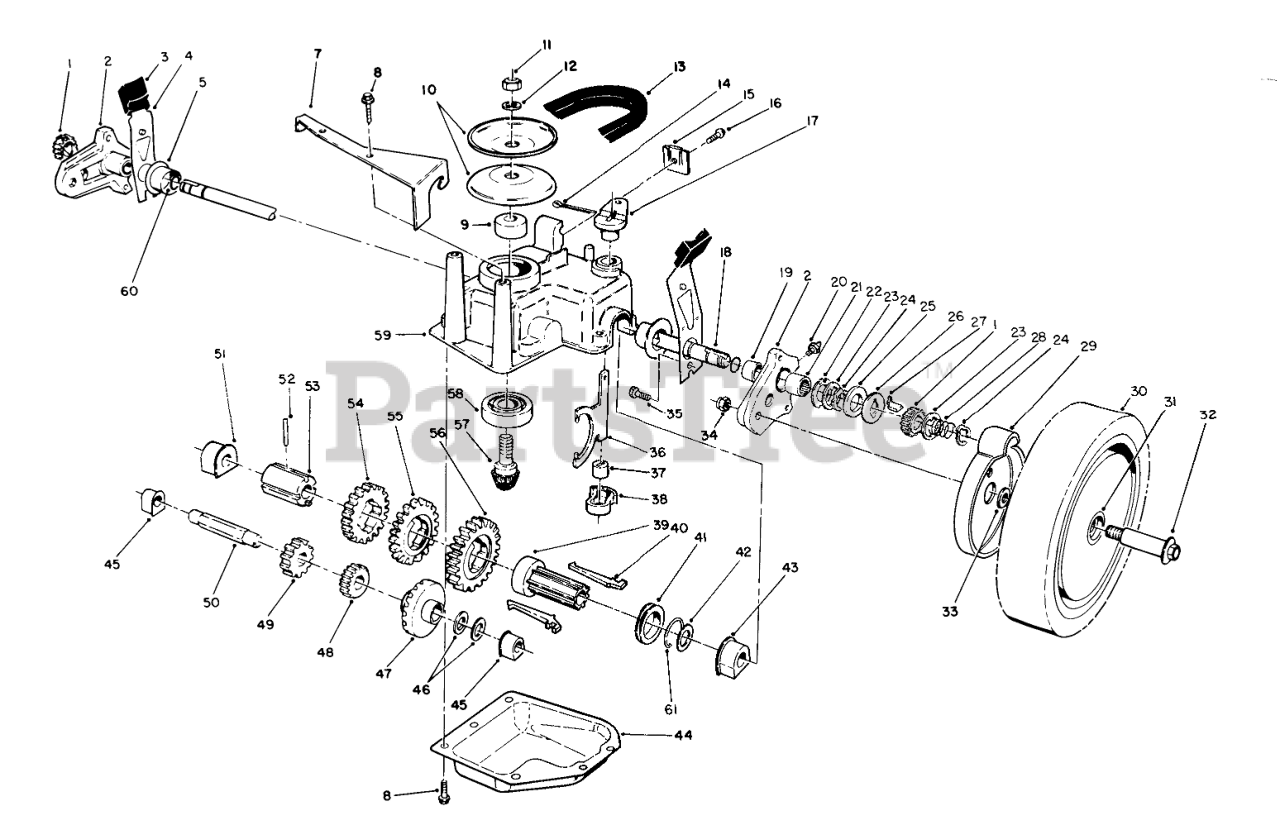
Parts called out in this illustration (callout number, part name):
1	GEAR-PINION
2	Pivot Arm Assembly (Incl. Ref #19, 20, & 21)
3	KNOB-ARM
4	SPRING ARM ASM SP
5	CAP-END
7	Bracket-Guide
8	SCREW-HWHTF
9	SPACER
10	Pulley Half
11	NUT-HEX
12	WASHER-FLAT
13	V-BELT E
14	PIN-COTTER
15	Cable Clamp
16	SCREW-HWHTF
17	SHIFT LEVER
18	SHAFT-OUTPUT
19	BUSHING
20	FITTING-GREASE
21	BEARING-ROLLER
22	WASHER-ARM, PIVOT
23	WASHER-THRUST, KEYED
24	RING-CLIP, LOCKING
25	RING-FRICTION
26	WASHER-CLUTCH
27	KEY-ROCKING, LH
28	SPRING-COMPRESSION
29	COVER-WHEEL
30	Wheel-Tire & Gear Ass-y (Incl. Ref. #31)
31	BUSHING
32	WHEEL BOLT
33	SPACER-COVER, WHEEL
34	Nut
35	SCREW-HWH
36	YOKE-SHIFT
37	BUSHING-YOKE
38	RETAINER-FORK, SHIFT
39	SLEEVE-KEY, SHIFT
40	KEY-SHIFT
41	COLLAR-SHIFT
42	WASHER-PLAIN
43	BUSHING-OUTPUT
44	Cover-Gearcase
45	BUSHING
46	WASHER-THRUST
47	Gear-Bevel
48	PINION-20T
49	PINION-25T
50	SHAFT-INTERMEDIATE
51	BUSHING
52	PIN-SPRING
53	SLEEVE-GEAR
54	GEAR-39T
55	GEAR-44T
56	GEAR-49T
57	Gear-Pinion
58	BEARING-BALL
59	CASE-GEAR, UPPER
60	O-RING
61	CLIP-SPRING
